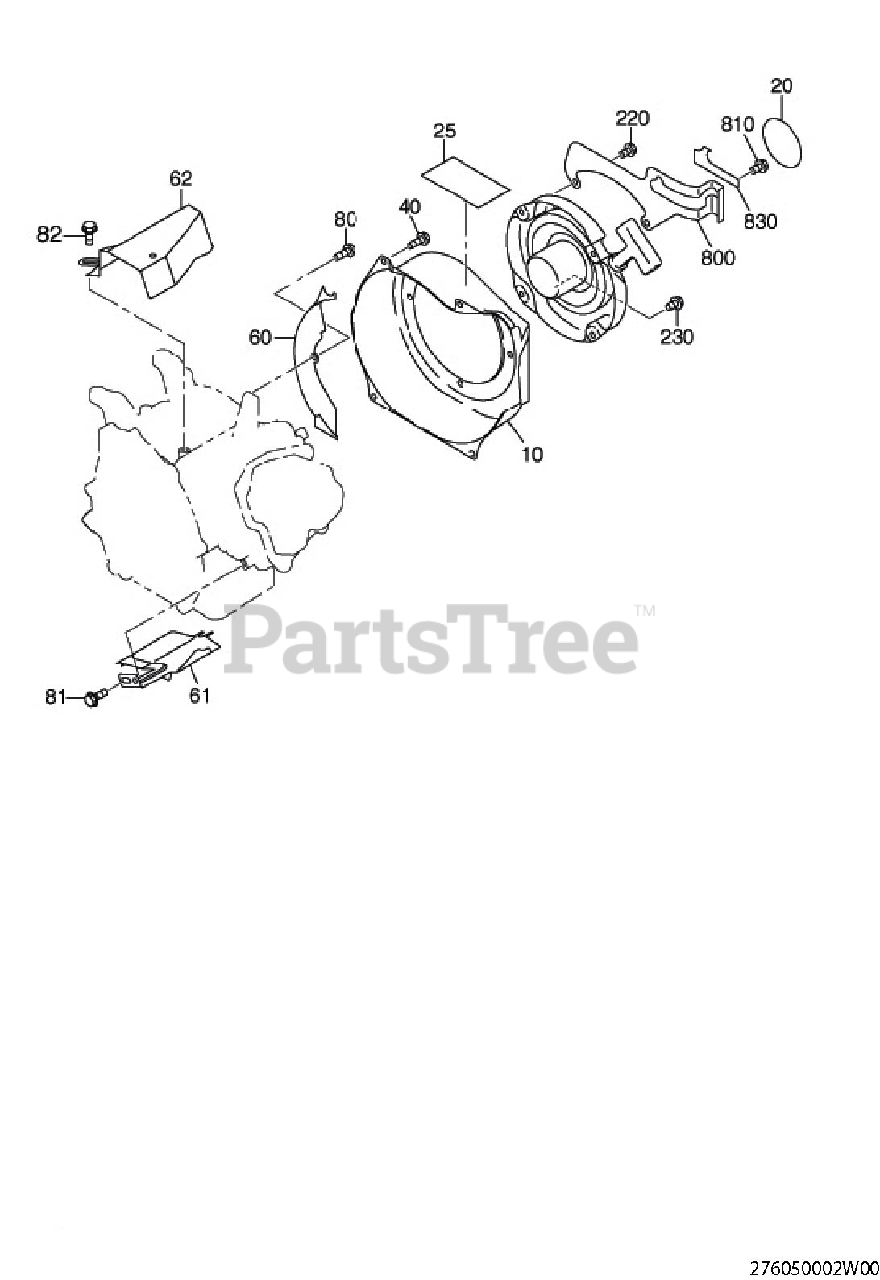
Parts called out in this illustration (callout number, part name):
10	BLOWER HOUSING CP
20	LABEL(TRADE MARK)
40	FLANGE BOLT
60	BAFFLE 1(CASE) CP
61	BAFFLE 2(HEAD)
80	FLANGE BOLT
81	FLANGE BOLT
220	FLANGE BOLT
